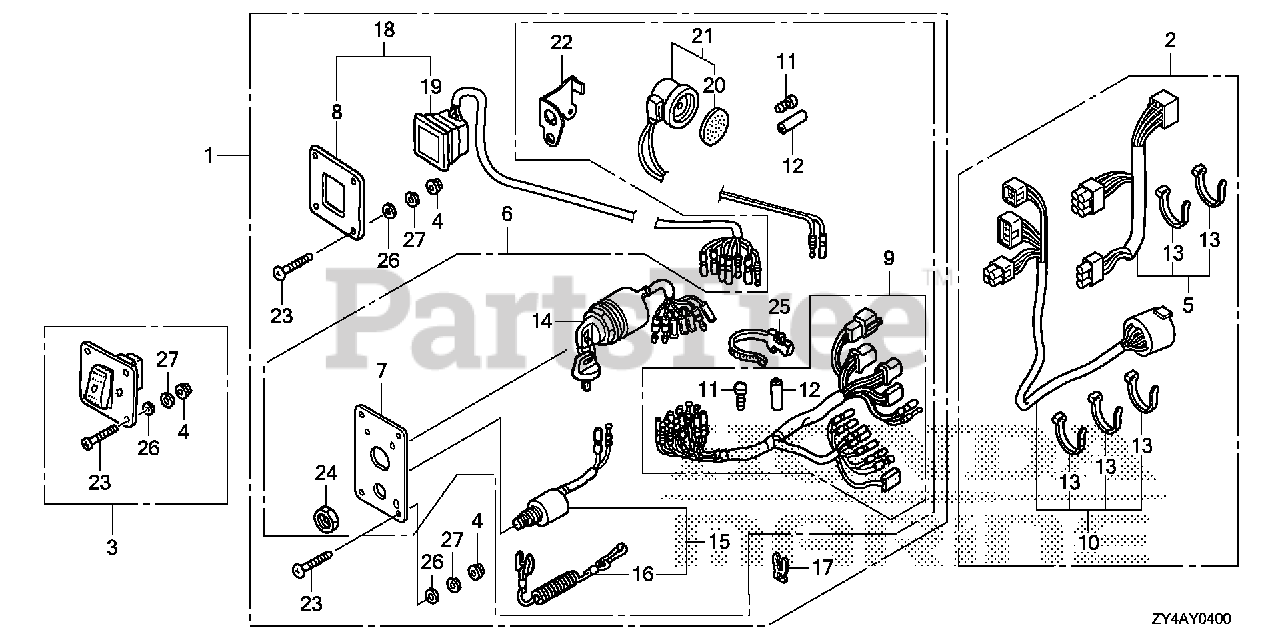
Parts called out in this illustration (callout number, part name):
1	PANEL KIT, SWITCH (4-LED) (B)
2	CABLE SET, PANEL INDICATOR (20FT)
2	CABLE SET, PANEL INDICATOR (25FT)
2	CABLE SET, PANEL INDICATOR (30FT)
3	SWITCH KIT, LIGHT
4	NUT, FLANGE (5MM)
5	WIRE ASSY., INDICATOR (20FT)
5	WIRE ASSY., INDICATOR (25FT)
5	WIRE ASSY., INDICATOR (30FT)
6	PANEL ASSY., SWITCH
7	PANEL, CONTROL
8	PANEL, CONTROL
9	HARNESS ASSY., SWITCH PANEL
10	CABLE ASSY., SWITCH PANEL (25FT) (NHK MEC)
10	CABLE ASSY., SWITCH PANEL (20FT) (NHK MEC)
10	CABLE ASSY., SWITCH PANEL (30FT) (NHK MEC)
11	PLUG, CONNECTOR (INNER)
12	PLUG, CONNECTOR (OUTER)
13	TIE, CABLE (2.4X92) (NATURAL)
14	SWITCH ASSY., COMBINATION
15	SWITCH ASSY., EMERGENCY STOP
16	WIRE, EMERGENCY
17	CLIP, EMERGENCY LOCK
18	PANEL ASSY., INDICATOR (4-LED)
19	LAMP ASSY., INDICATION (4-LED)
20	PLATE, TURN SIGNAL BUZZER
21	BUZZER, WARNING
22	BRACKET, BUZZER
23	SCREW, PAN (5X40)
24	NUT, HEX. (16MM)
25	BAND, WIRE HARNESS (150MM) (NATURAL)
26	WASHER, PLAIN (5MM)
27	WASHER, SPRING (5MM)
